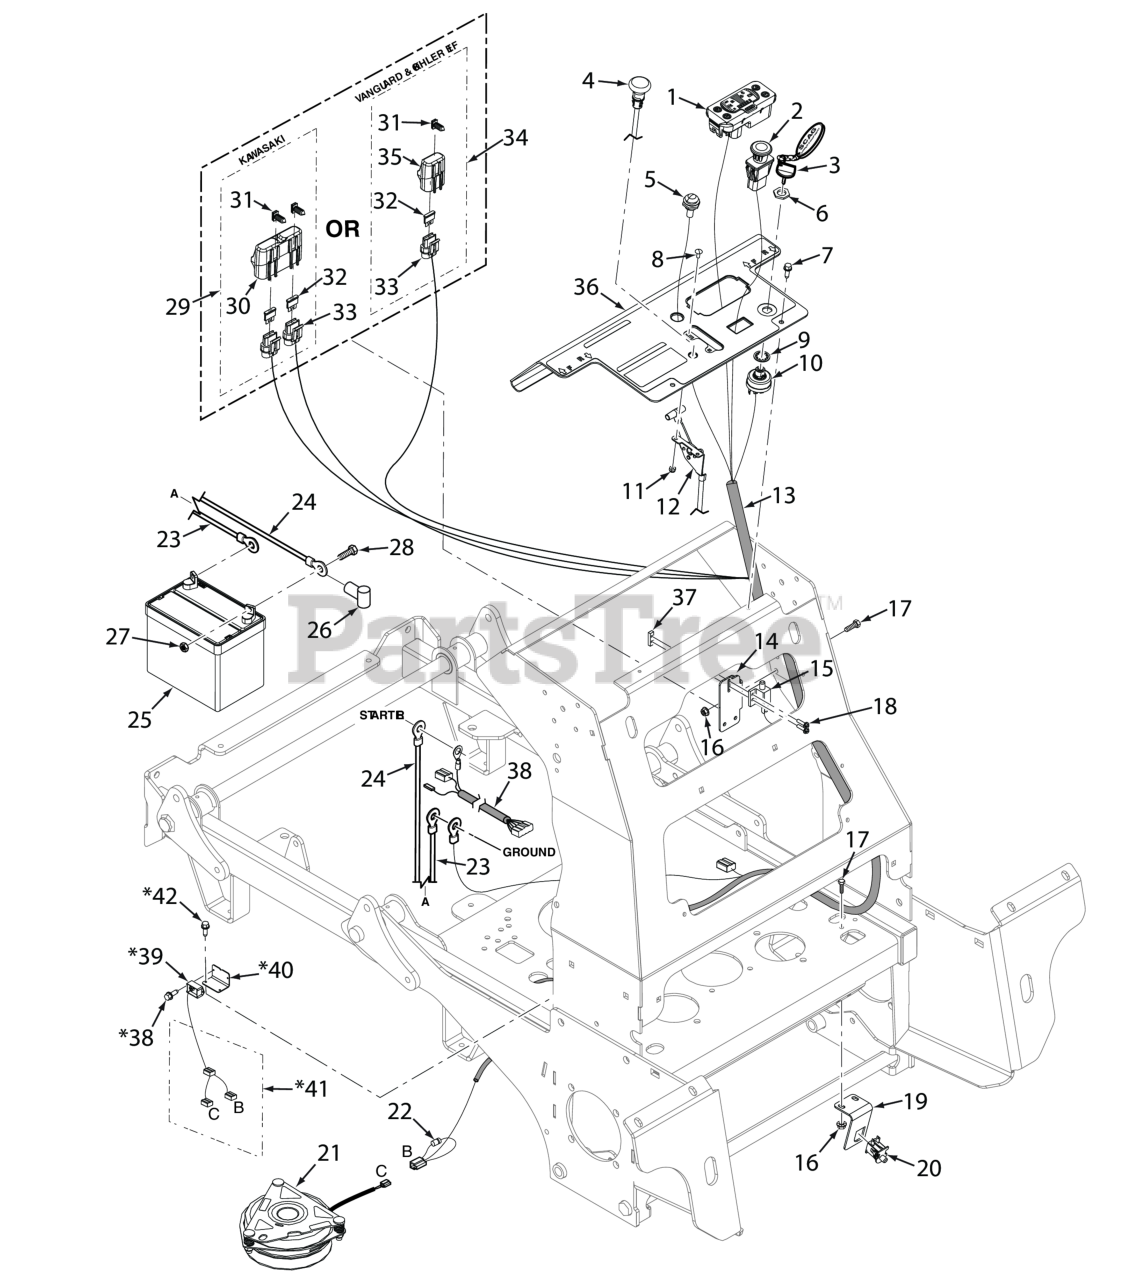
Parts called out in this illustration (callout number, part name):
1	Tiger Eye, Cluster Gauge
2	Switch, PTO - 10 Amp
3	Key, Assembly w/Fob
4	Choke Control (excludes EFI models)
5	Indicator Light, Glow Plugs (Includes Mounting Hardware)
6	Nut, 5/8-32 Special
7	Screw, Self-Tapping 1/4-20 x 3/4
8	Bolt, Carriage #10-24 x 1/2"
9	LOCK WASHER, 5/8" INTERNAL TOOTH
10	KEY SWITCH(INCLUDES MOUNTING HARDWARE)
11	Nut, Elastic Stop #10-24
12	Throttle Control, E-Gov (26FT, 38FX-EFI)
13	Wire Harness, SVRII
14	Bracket, Neutral Switch
15	Switch, Interlock, Park Brake Normally Open
16	NUT, 1/4-20 SERRATED FLANGE HEX HEAD
17	BOLT, HEX HEAD, 1/4-20 X 3/4 GR.5
18	Screw, Hex-Slotted Washer Head #10 32 x 3/4"
19	Switch Bracket, Operator Presence
20	SWITCH, NEUTRAL INTERLOCK
21	Clutch w/Tag GT3.5--FE05 (61)
22	Diode, 600V 6 Amp
23	Battery Cable, 39" Black (26EFI) - Kohler
24	Battery Cable, 44" Red w/Braid (26EFI) - Kohler
25	Battery, 350 CCA (not available through Scag)
26	RUBBER BOOT
27	Nut, 1/4 - 20 Hex
28	BOLT, HEX HEAD, 1/4-20 X 3/4 GR.5
29	Double Fuse Assy.
30	Cover, Sealed Double
31	Clip, Fuse Holder
32	FUSE, 20 AMP BLADE TYPE AUTOMOTIVE
33	Fuse Holder Assembly
34	Single Fuse Assy., Excluding Fuse
35	Cover, Sealed Single
36	Control Panel with Decal
37	Plate, Threaded
38	Wire Harness Adapter, Kawasaki - 22FX & 23FX
39	Soft Start Module, Clutch
40	Mounting Bracket, Soft Start Module
41	Wire Harness, Clutch Soft Start
42	Screw, #10-32 x .563 Shakeproof
